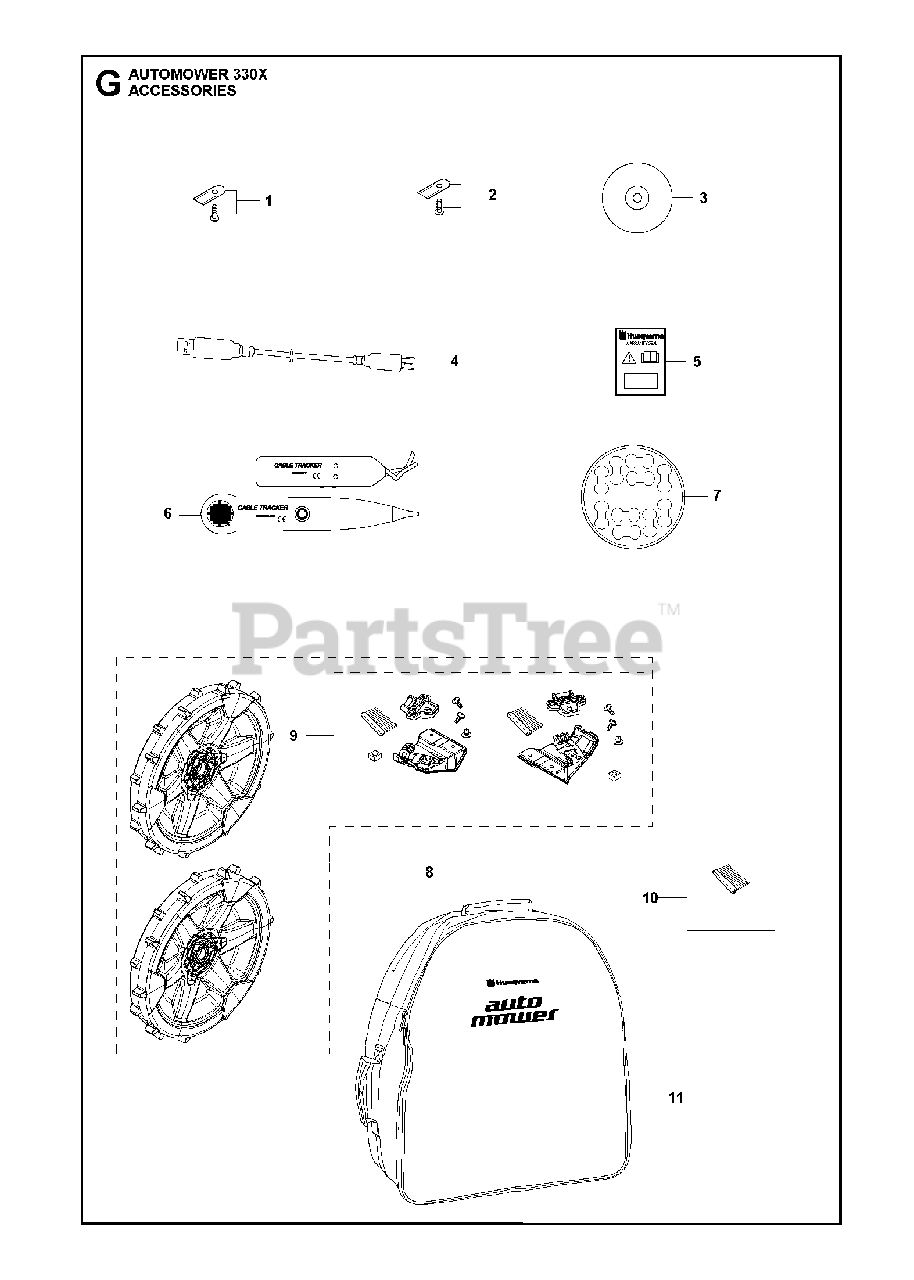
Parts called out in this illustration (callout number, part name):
1	BLADE
1	BLADE KIT
1	BLADE - 30 PCS
1	BLADE - BULK PACK 500 PCS
2	BLADE 9PCS EXTRA THICK
2	Blade Set, 9 Piece Extra Thick
2	BLADE CARBON STEEL, THICK BLAD
2	BLADE 300PCS -SINGLE HOLE THIC
5	LABEL WARRANTY SEAL DEALER
5	LABEL WARRANTY SEAL KIT 10 PK
6	TEST EQUIPMENT
